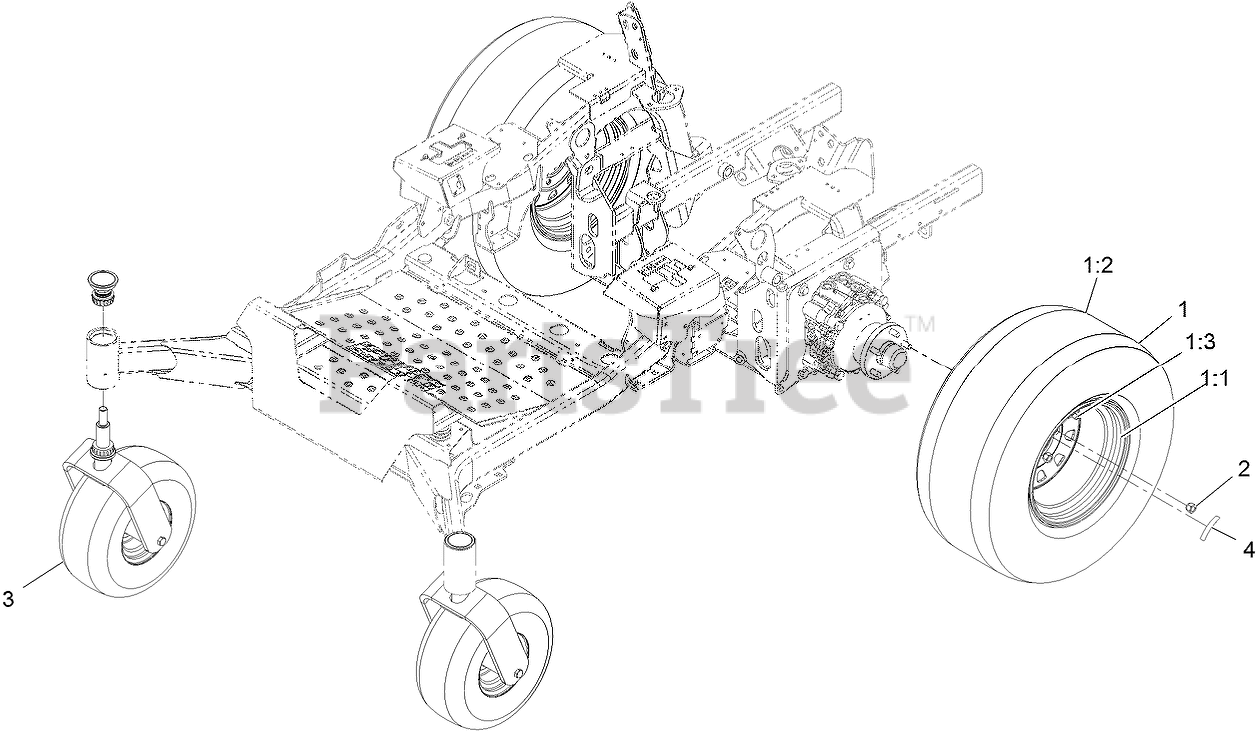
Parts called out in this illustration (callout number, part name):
1	ASM-TIRE 26X12-12, 1.0 OF
1:1	RIM ASM, 1.0 OFFSET
1:3	Stem-Valve
2	NUT-LUG
3	ASM, Wheel Caster
4	DECAL-TORQUE, WHEEL NUT
